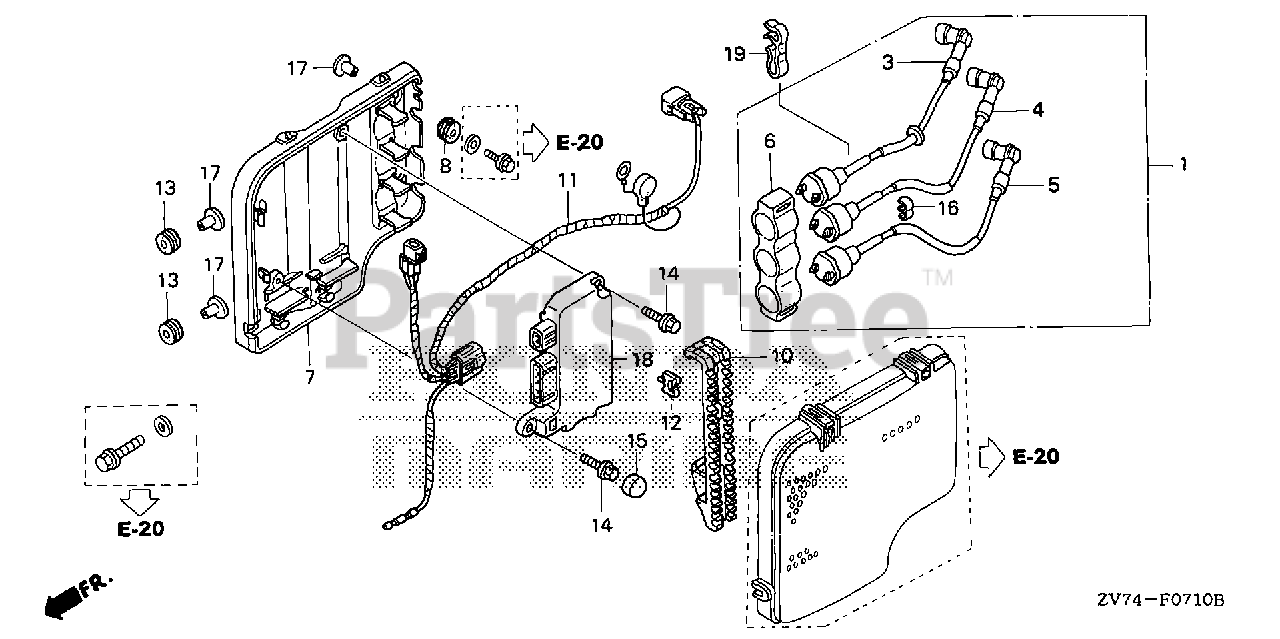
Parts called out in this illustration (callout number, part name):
1	COIL ASSY., IGNITION
3	COIL, IGNITION (1)
4	COIL, IGNITION (2)
5	COIL, IGNITION (3)
6	SUSPENSION, IGNITION COIL
7	CASE, IGNITION CONTROL MODULE (CDI)
8	GROMMET, MODULE IGNITION CONTROL CASE (CDI)(B)
10	BRACKET, CONNECTOR (A)
11	CABLE ASSY., IGNITION CONTROL MODULE (2) (CDI)
12	CLIP, TURN SIGNAL WIRE
13	GROMMET, CASE (LOWER)
14	BOLT, FLANGE (6X20)
15	CAP, BOLT (6MM)
16	CLIP, HIGH TENSION CORD
17	COLLAR, MODULE IGNITION CONTROL CASE (CDI)
18	MODULE, IGNITION CONTROL (CDI)
19	CLAMP, WIRE
